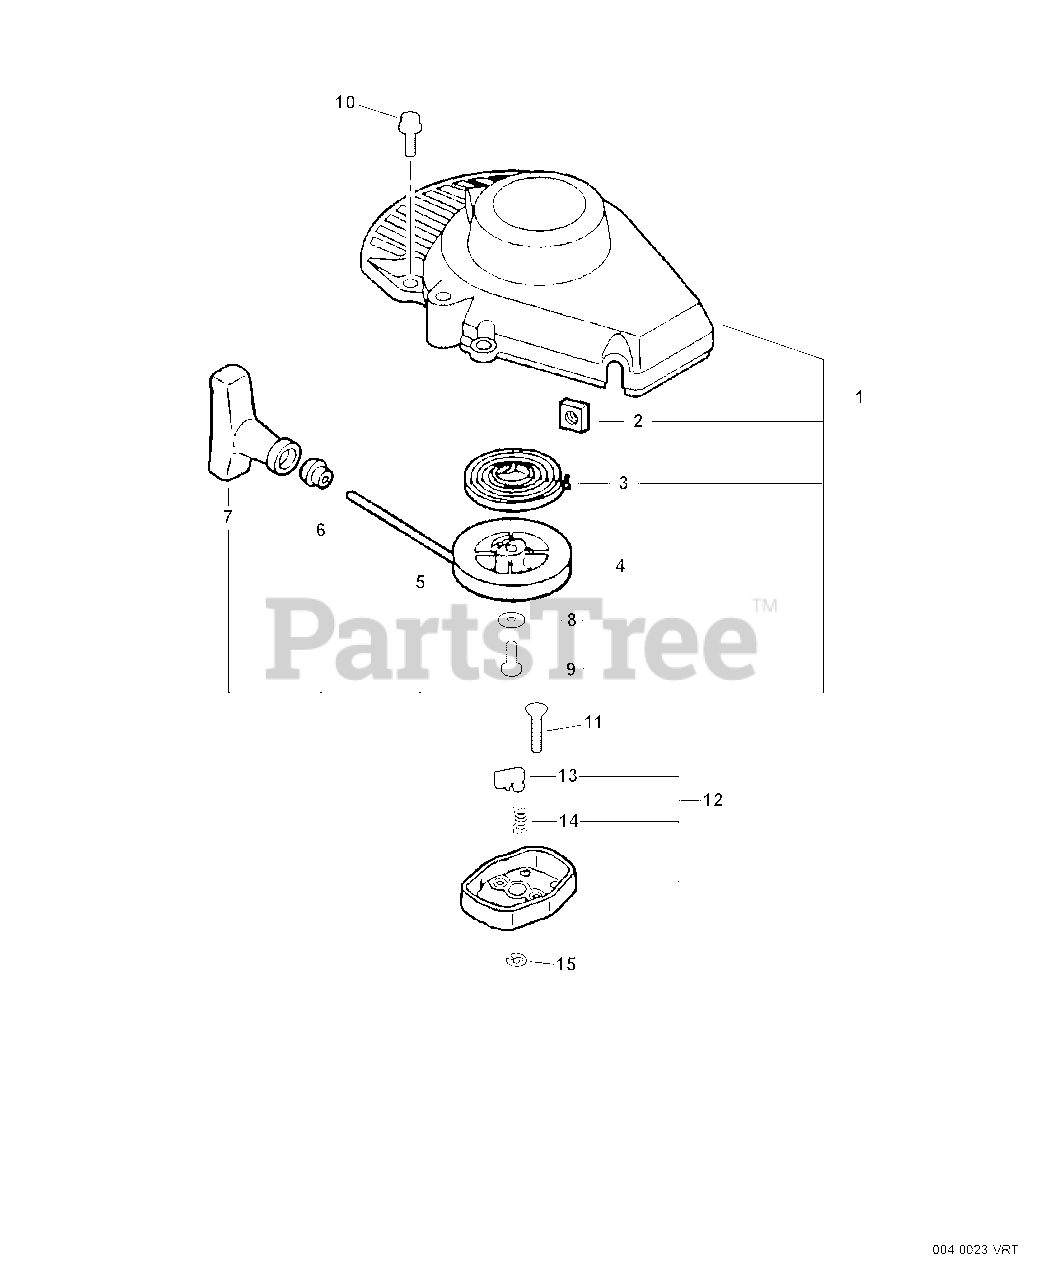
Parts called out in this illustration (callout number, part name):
1	STARTER ASSY
2	NUT - 5 -- SQUARE
3	SPRING, REWIND
4	REEL, ROPE
5	ROPE, STARTER
6	GUIDE, ROPE
7	GRIP, STARTER
8	WASHER
10	SCREW - 5X16
11	SCREW - 6X14
12	STARTER PAWL ASSY
13	PAWL, STARTER
14	SPRING, RETURN
15	RING, RETAINING - 4
